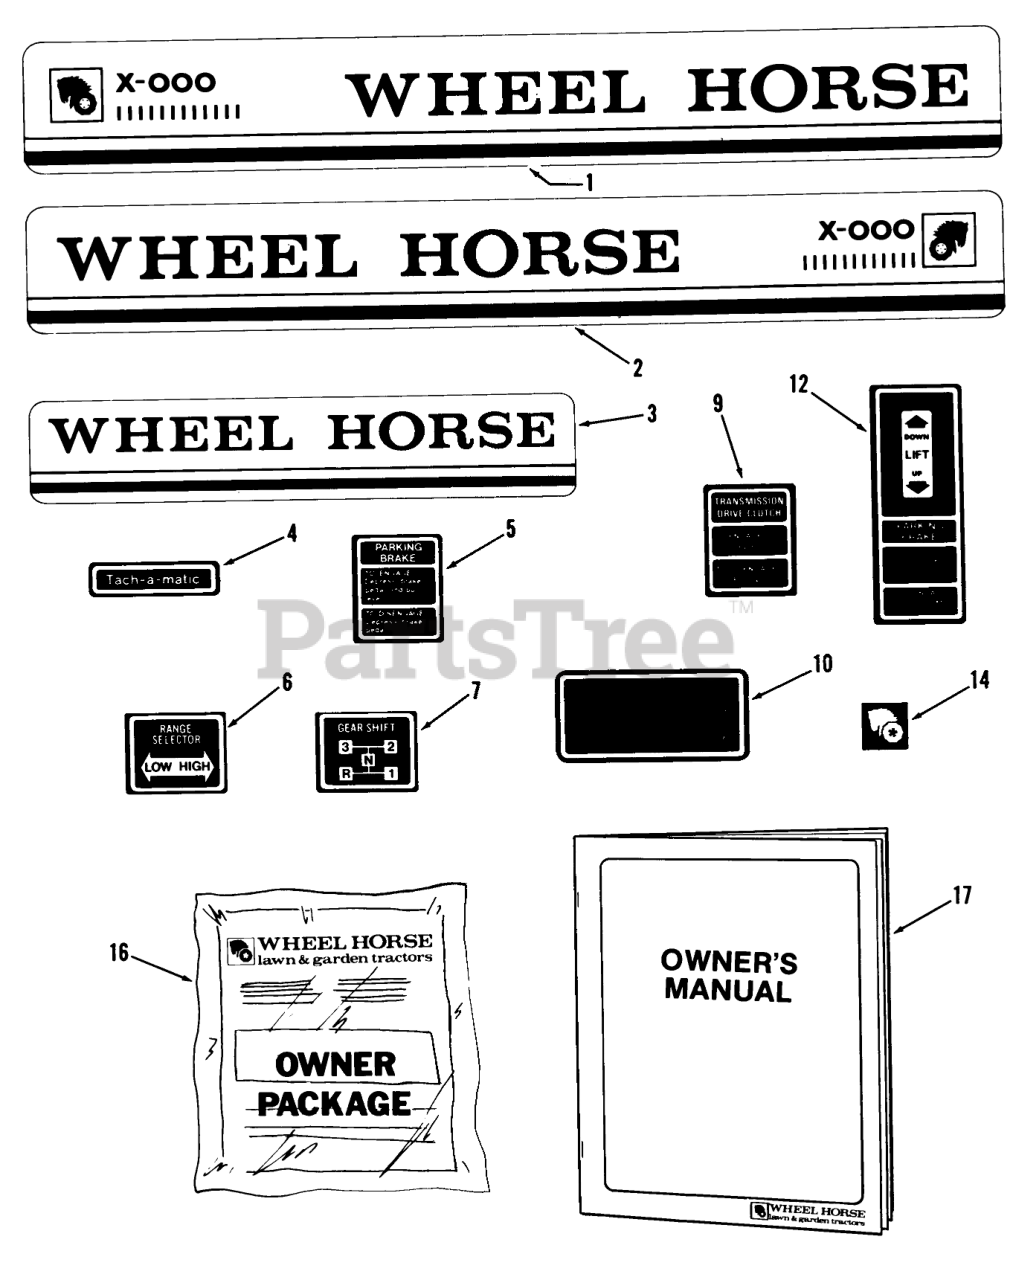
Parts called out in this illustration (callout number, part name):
1	Decal LH C-105 8-Speed
1	Decal LH C-125 8-Speed
1	Decal LH C-165 8-Speed
1	Decal LH C-145 Automatic
1	DECAL-HOOD C-175 LH
2	DECAL-HOOD C-105 RH
2	DECAL-HOOD C-125 RH
2	Decal RH C-165 8-Speed
2	Decal RH C-145 Automatic
2	Decal RH C-175 Twin Automatic
3	DECAL-REAR
4	DECAL-TACHAMATIC
5	DECAL-PARKING BRAKE
6	DECAL HI-LO
7	DECAL-SHIFT
9	Decal-Transmission Clutch
10	Decal-Maintenance
12	Decal-Parking Brake & Lift
14	DECAL-LOGO
16	Loose Parts Package C-105, C-125, C-145 Only
16	Loose Parts Package C-165 Only
16	Loose Parts Package C-175 Twin Only
17	Owner-s Manual-Tractor
